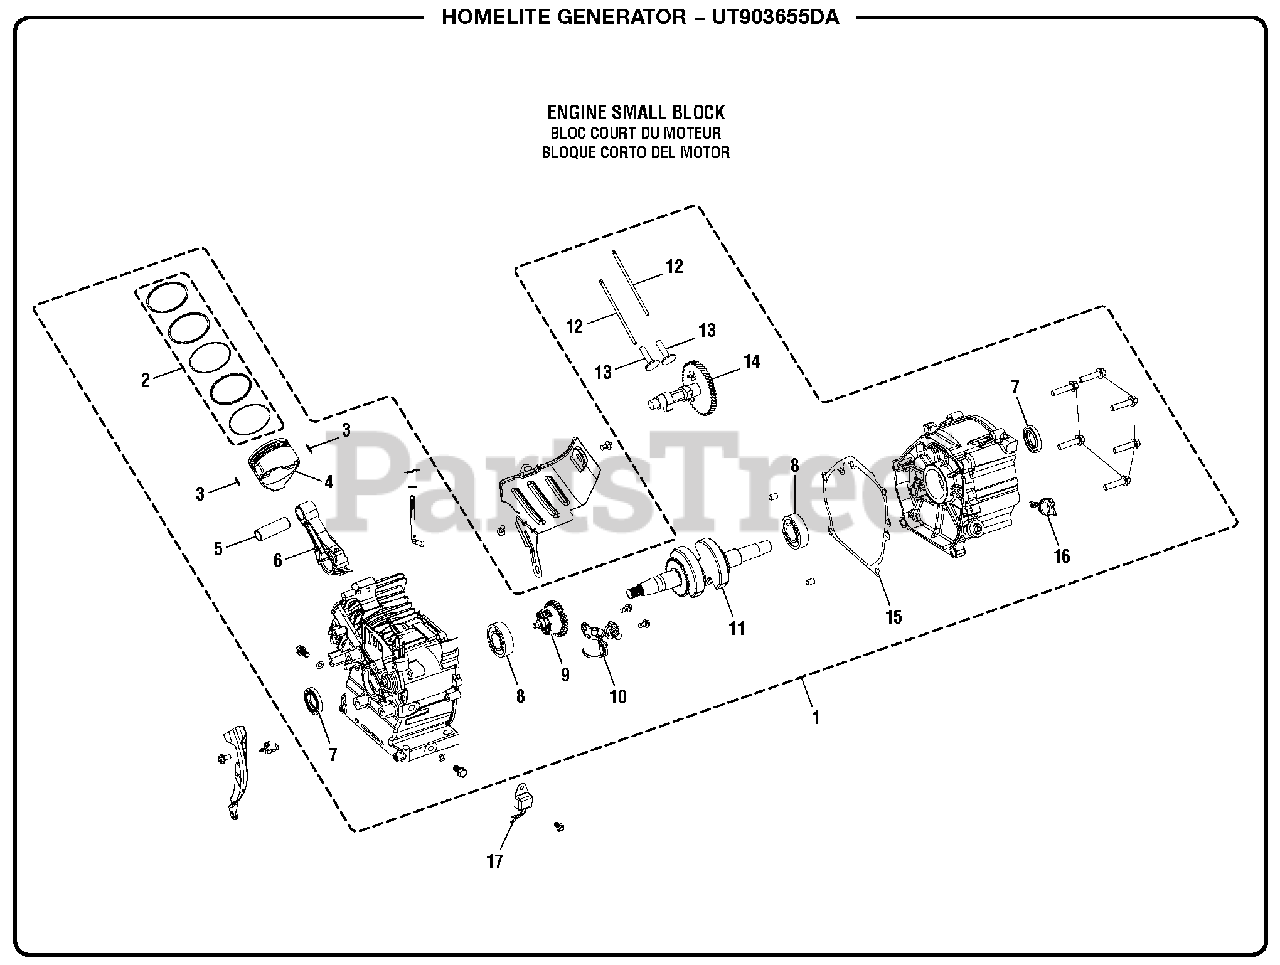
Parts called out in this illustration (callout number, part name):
1	Engine Small Block
2	Piston Ring Set
3	Piston Clip
4	Piston
5	Piston Pin
6	Connecting Rod Assembly
7	Oil Seal
8	Ball Bearing
9	Governor Assembly
10	Switch Assembly (Oil Level)
11	Crankshaft Assembly
12	Valve Lifter Assembly
13	Valve Tappet
14	Camshaft Assembly
15	Casecover Gasket
16	Dipstick
17	Amplifier
18	Valve Cover
